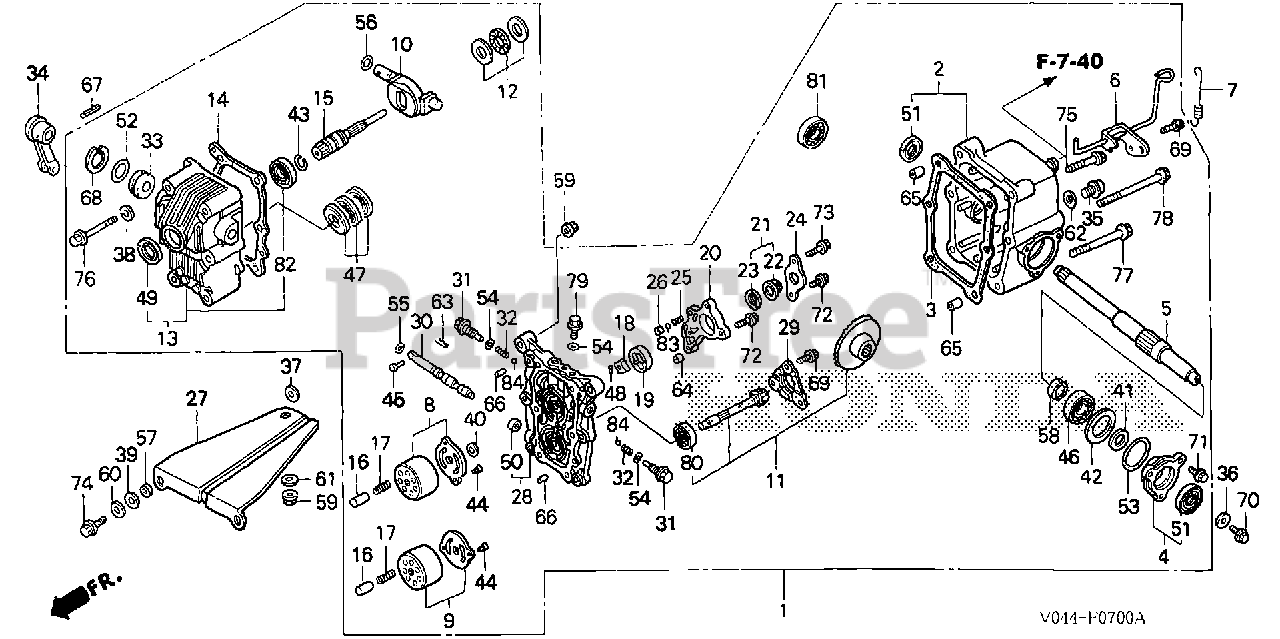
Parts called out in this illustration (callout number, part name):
1	TRANSMISSION ASSY.
2	CASE, RR. TRANSMISSION
3	GASKET, RR. TRANSMISSION CASE
4	HOLDER, OIL SEAL
5	SHAFT, CROSS
6	ARM, NEUTRAL VALVE
7	SPRING, NEUTRAL VALVE
8	PLATE SET, PUMP CYLINDER
9	PLATE SET, MOTOR CYLINDER
10	BOWL SET, CONTROL
11	GEAR SET, MOTOR SHAFT & BEVEL
12	BEARING SET, THRUST NEEDLE
13	CASE, PUMP
14	GASKET, PUMP CASE
15	SHAFT, PUMP
16	PISTON, PUMP (HOLE DEPTH=18MM)
17	SPRING, PISTON (5.8X34.5)
18	ROTOR, TROCHOID
19	VANE, TROCHOID
20	HOUSING, TROCHOID
21	FILTER ASSY., SUCTION
22	FILTER, SUCTION
23	SEAL, RUBBER
24	PLATE, FILTER CAP
25	SPRING, RELIEF VALVE
26	SEAT, RELIEF VALVE
27	PLATE, TRANSMISSION MOUNTING
28	PLATE, DISTRIBUTOR
29	HOLDER, BEARING
30	SPOOL, NEUTRAL VALVE
31	BOLT, CHECK VALVE
32	SPRING, CHECK VALVE
33	BUSH, CONTROL BOWL (B)
34	ARM, CLUTCH
35	BOLT, PLUG (14MM)
36	WASHER (6X17)
37	WASHER (8MM)
38	WASHER, SEALING (9X16X1.5)
39	WASHER, WAVE (12MM)
40	WASHER, THRUST (8MM)
41	WASHER, PLAIN (15MM)
42	SHIM A, BEVEL GEAR (1.5MM)
42	SHIM B, BEVEL GEAR (1.55MM)
42	SHIM C, BEVEL GEAR (1.6MM)
42	SHIM D, BEVEL GEAR (1.65MM)
42	SHIM E, BEVEL GEAR (1.7MM)
42	SHIM F, BEVEL GEAR (1.75MM)
43	CLIP, BEARING
44	PIN, DOWEL (3X5.8)
45	PIN, NEUTRAL VALVE
46	BEARING, RADIAL BALL (6904) (NTN CORP.)
47	BEARING, THRUST BALL (51204)
48	ROLLER (2.5X11.8)
49	OIL SEAL (17X30X5) (NIPPON)
50	DUST SEAL (9X15X5)
51	OIL SEAL (15X28X7)
52	O-RING (25X2.4)
53	O-RING (34.6X1.9)
54	O-RING (11X1.9)
55	O-RING (5.8X1.9)
56	O-RING (11.8X1.9)
57	COLLAR, TRANSMISSION MOUNT (8X12X4.7)
58	COLLAR, BEVEL GEAR
59	NUT, FLANGE (8MM)
60	WASHER, PLAIN (8MM)
61	WASHER, PLAIN (8MM)
62	WASHER, DRAIN PLUG (14MM)
63	PIN, LOCK (4MM)
64	PIN A, DOWEL (8X10)
65	PIN, DOWEL (10X12)
66	PIN, DOWEL (5X8)
67	PIN, SPRING (4X28)
68	CIRCLIP (INNER) (30MM)
69	BOLT, FLANGE (6X12) Use from Engine SN 2086984.
70	BOLT, FLANGE (6X16) Use from Engine SN 2056820.
71	BOLT, FLANGE (6X16)
72	BOLT, FLANGE (6X25)
73	BOLT, FLANGE (6X32)
74	BOLT, FLANGE (8X40) Use up to Engine SN 1003236.
75	BOLT, FLANGE (8X45)
76	BOLT, FLANGE (8X65)
77	BOLT, FLANGE (8X70)
78	BOLT, FLANGE (8X90)
79	BOLT, FLANGE (10X16)
80	BEARING, RADIAL BALL (6001)
81	BEARING, RADIAL BALL (6002)
82	BEARING, RADIAL BALL (6003)
83	BALL, STEEL (#6) (3/16)
84	BALL, STEEL (#8) (1/4)
